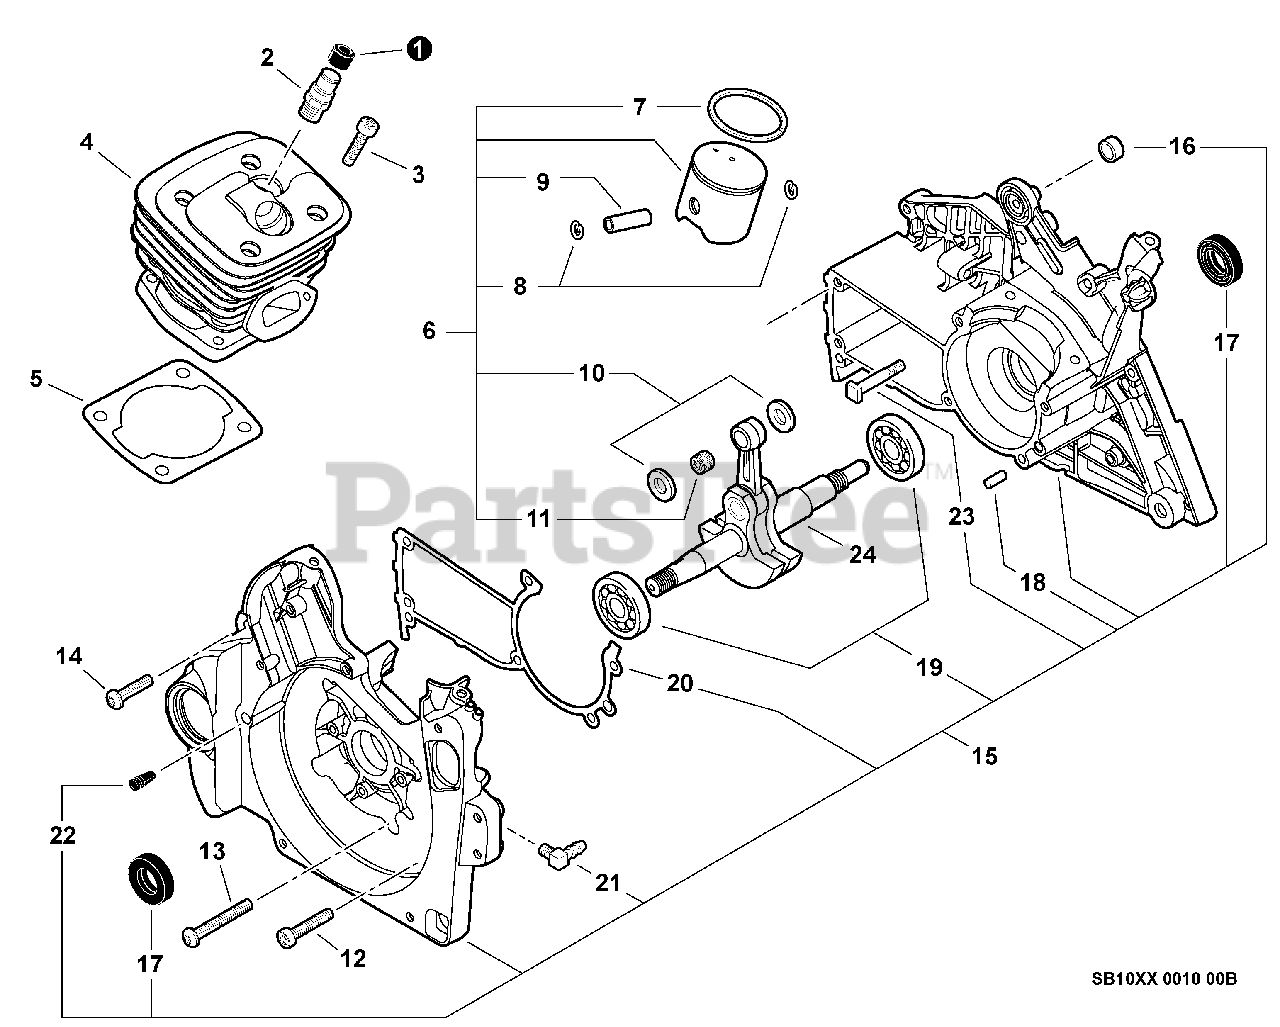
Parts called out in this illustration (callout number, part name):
1	COVER, DUST
2	DECOMPRESSION ASSY
3	SCREW - 5X25
4	CYLINDER
5	GASKET, CYLINDER
6	PISTON KIT
7	RING, PISTON
8	RING, RETAINING - 1
9	PIN, PISTON
10	WASHER, THRUST
11	BEARING, NEEDLE
12	SCREW - 5X25
13	SCREW - 5X35 -- TAPPING
14	SCREW - 5X20
15	CRANKCASE KIT
17	SEAL, OIL
18	PIN - LOCATING
19	BEARING, BALL
20	GASKET, CRANKCASE
21	FITTING, GREASE
22	VENT, TANK
23	STUD, GUIDE BAR
24	CRANKSHAFT ASSY
